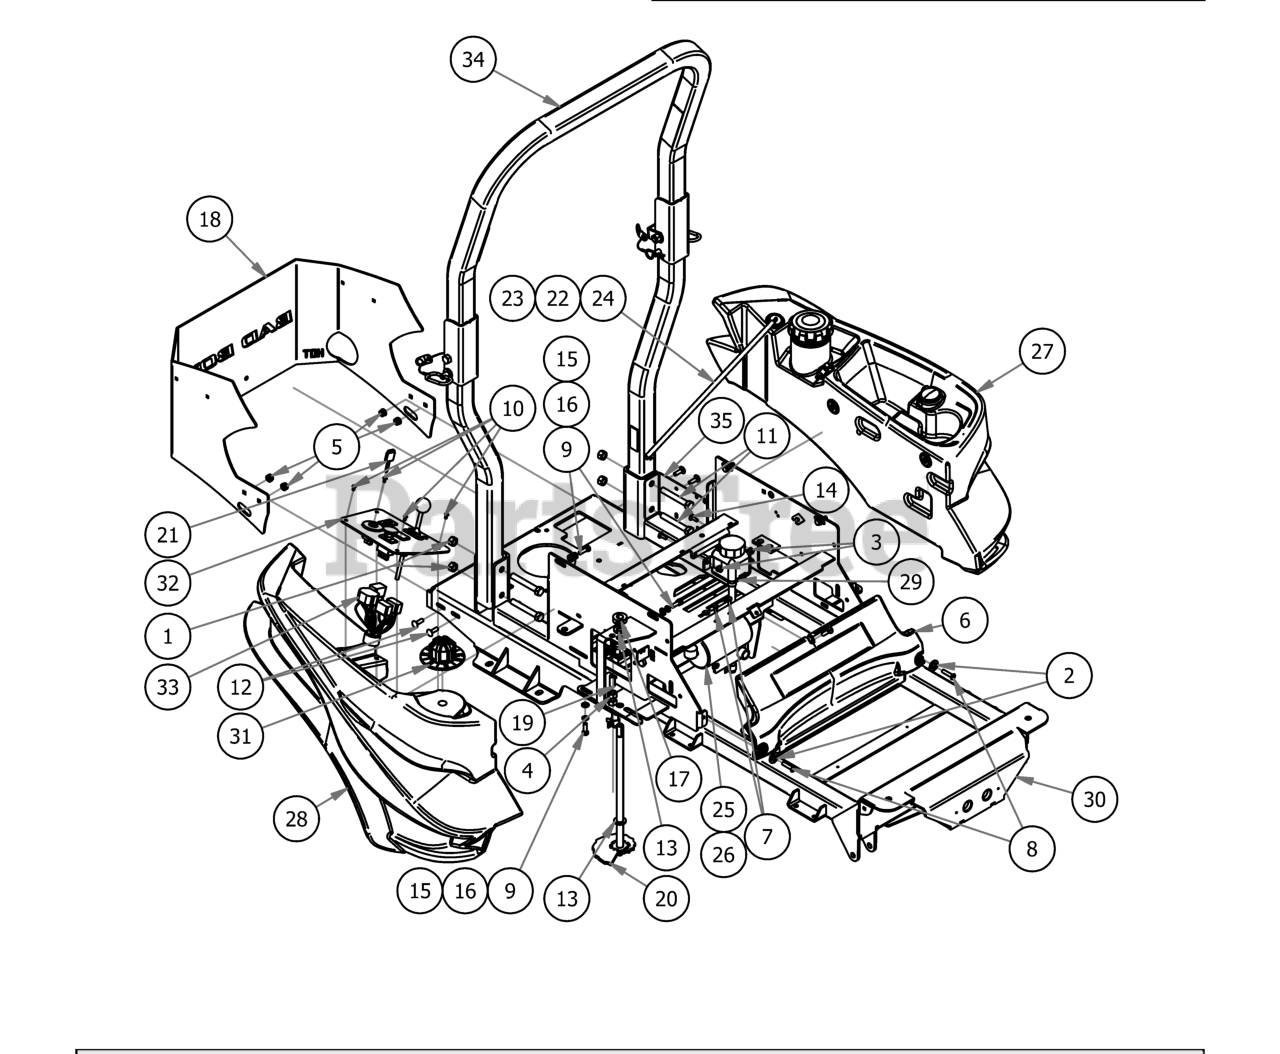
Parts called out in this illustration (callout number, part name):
1	1/2" Center Lock Nut
2	1/2" Flat Washer Flat Black
3	1/4-20 Nylon Insert flange Nut
4	1/2" Hex Nut
5	5/16-18 Nylon Flange Nut
6	Front Cover
7	M6-1.0 X 16MM Hex Bolt
8	5/16-18x1.5 torx cutter -Black
9	5/16" x 1" Bolt
10	10-32 x 3/8" Button Socket Head Bolt
11	1/2-13 x 3 1/2 GR 5 Hex Bolt
12	5/16" x 1" Carriage Bolt
13	.630 ID x 1.122 OD x .142 THK Plastic Washer
14	1/4" x 3/4" Carriage Bolt
15	5/16" Flat Washer
16	5/16" Lock Washer
17	5/8" Split Collar
18	2017 ZT Rear Plate
19	Dial Rod Plunger
20	ZT Deck Height Bar Assembly
21	Ignition Key
22	Maverick Honda Fuel Line Assy-54"
23	Maverick Kohler Fuel Line Assy-37"
24	Maverick Kawasaki Fuel Line Assy-15"
25	ZT/Mav EPA Cannister Assy
26	2019 Honda Maverick EPA Cannister Assy
27	Left Fuel Tank
28	Right Side Console
29	Hydro Tank Assembly
30	2018 Maverick Frame
31	MZ/ZT Deck Height Dial
32	2019 ZT/Maverick Control Panel Assembly
33	Wiring Harness
34	2016 2x2 ROPS
35	Honda Rectifier Mount
